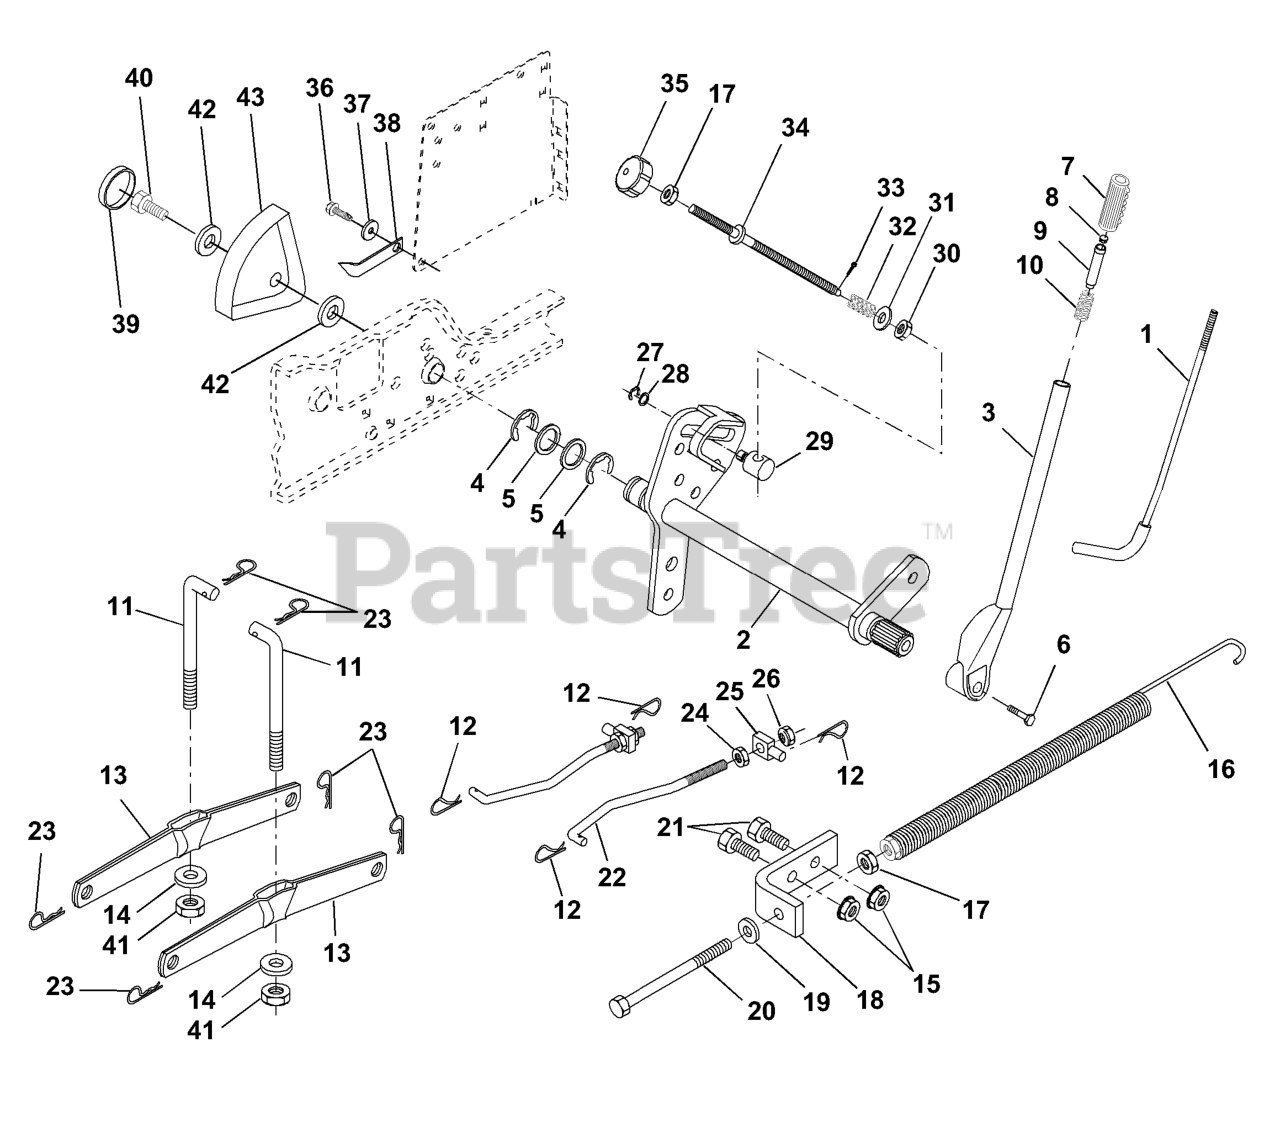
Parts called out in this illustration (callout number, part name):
1	LEVER ROD LT
2	SHAFT ASM, LIFT VGT
3	LIFT LEVER KIT
5	Washer 29/32 x 1-1/4 x 16 Ga.
6	BOLT
7	GRIP HANDLE
8	PLUNGER BUT KIT
9	PLUNGER BUT KIT
10	SPRING**
11	LINK LIFT
12	SPRING RETAINER
13	ARM.REAR.SUSPENSION
14	BEARING PIVOT
15	NUT
16	LIFT SPRING
17	NUT
19	WASHER
21	BOLT
22	FRONT LINK
23	RETAINER-SPRNG RB
24	NUT.HEX.JAM.1/2-13
25	TRUNION
26	NUT.LK.W/WSH.1/2.
27	Ring, Klip #T5304-37
28	Washer 15/32 x 3/4 x 16 Ga.
29	TRUNION LT
32	SPRING.COMP.INF.H
33	COTTER PIN
34	ROD.LIFT.ADJUSTABLE
35	KNOB INF 3/8-16
36	SCREW
38	POINTER HGT
40	SCREW.THDROL.5/16-18X3/4.TTY
41	NUT CROWNLOCK 3/8-24
43	HEIGHT INDICATOR
